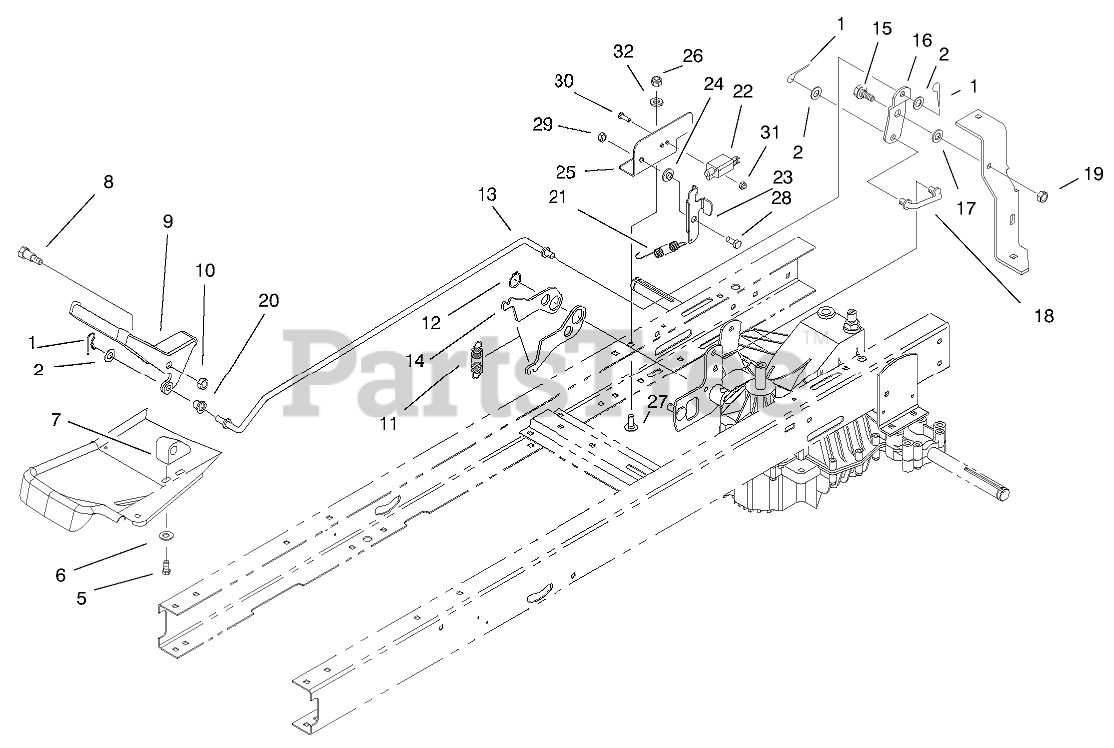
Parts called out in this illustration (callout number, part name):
1	PIN-COTTER
2	WASHER-FLAT
5	SCREW-PLASTITE
6	WASHER-FLAT
7	BLOCK-PIVOT
8	SCREW-SHOULDER, HH
9	PEDAL-CONTROL, SPEED
10	NUT-LOCK, NI
11	SPRING-EXTENSION
12	RING-SNAP
13	ROD-SPEED CONTROL,1744
14	NEUTRAL RETURN LEVER
15	BOLT-SHOULDER
16	BELLCRANK
17	WASHER-BELLEVILLE
18	LINK-SPEED/DIRECT CONTROL
19	NUT-LOCK, NI
20	BUSHING-FLANGED
21	SPRING-EXTENSION
22	SWITCH-POLE, SINGLE
23	BRACKET-PIVOT
24	WASHER-STEPPED
25	BRACKET-ADJUSTMENT
26	NUT-LOCK, NI
27	SCREW-CARR
28	SCREW-HHF
29	NUT-LOCK, NI
30	SCREW-SHH
31	NUT-LOCK
32	WASHER-PLAIN
